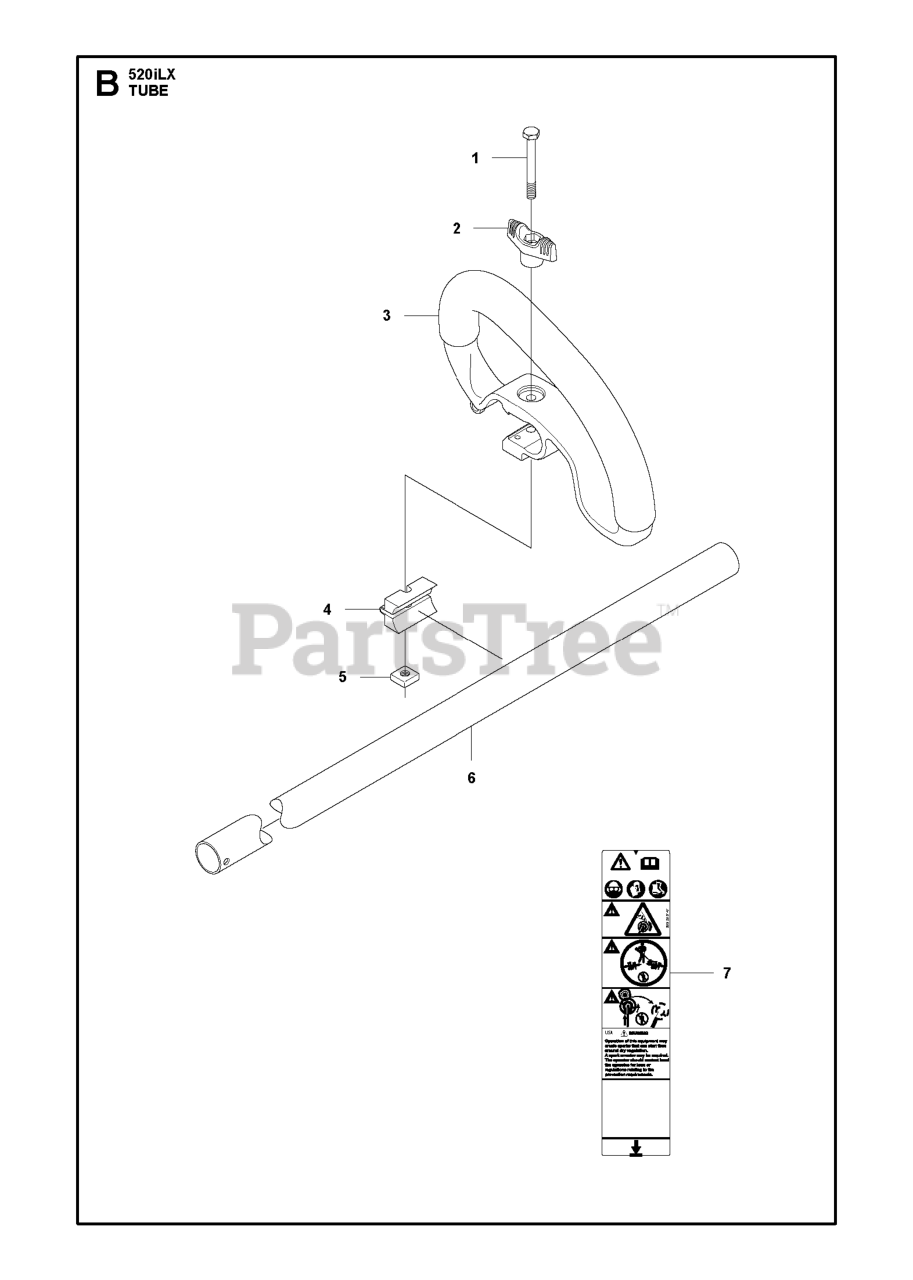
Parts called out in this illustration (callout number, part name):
1	SCREW M6X50
4	SPACER PLASTIC
7	LABEL WARNING TRIMMERS AND BRU
